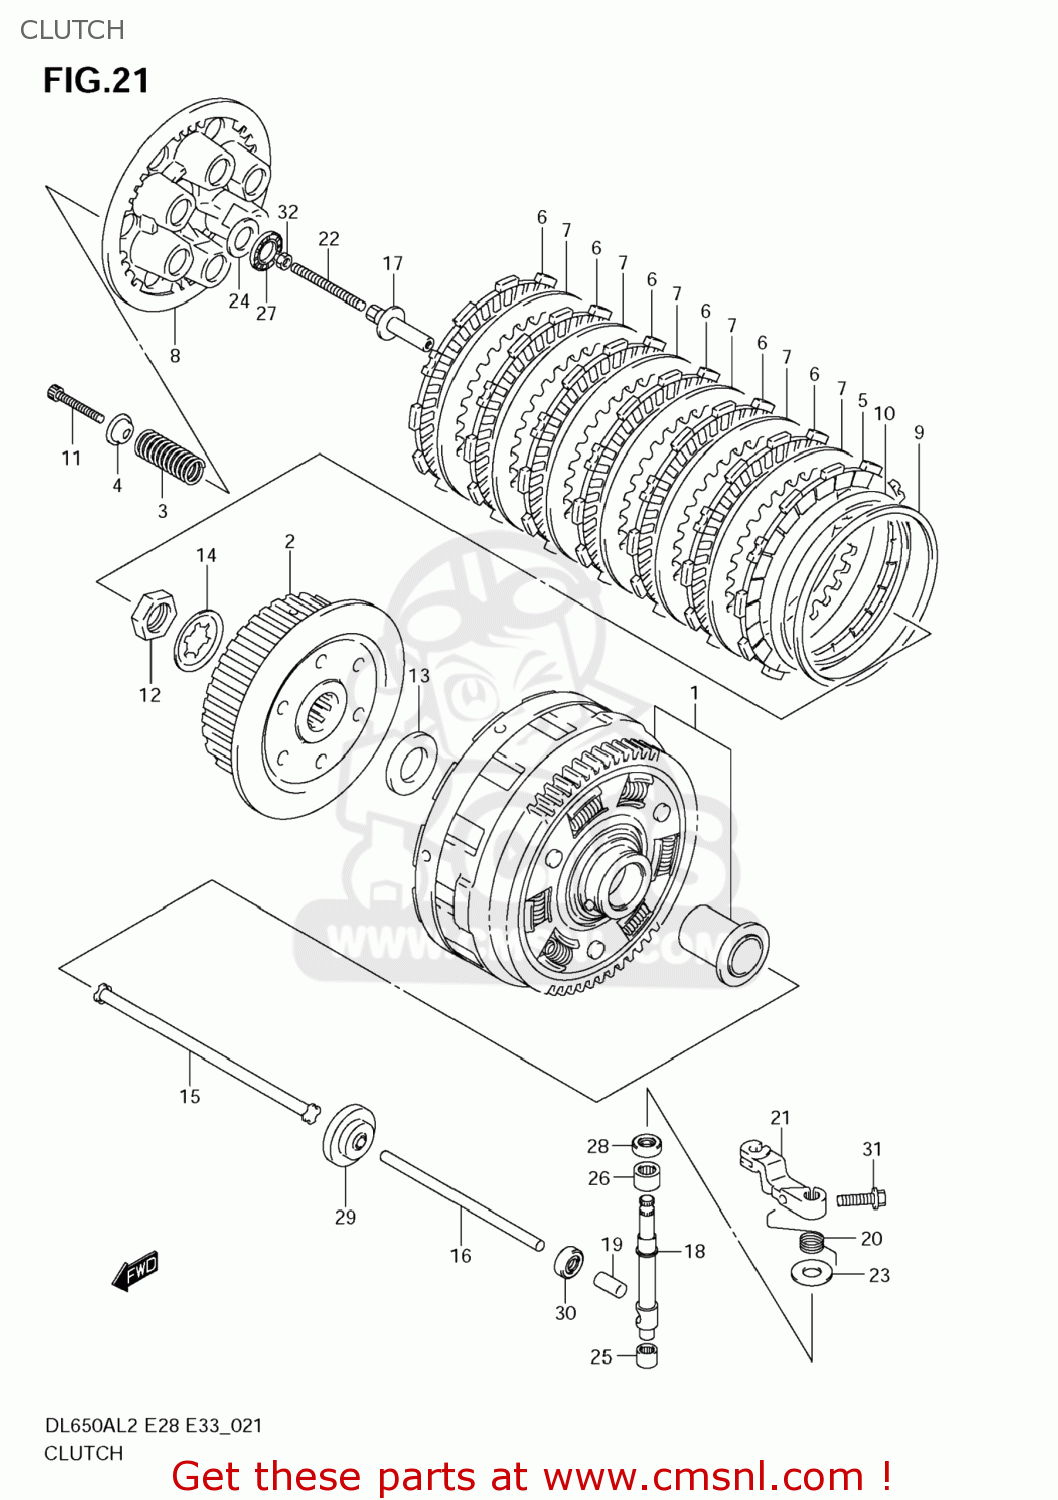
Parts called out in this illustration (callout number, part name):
1	GEAR ASSY,PRI DRIVEN
2	HUB,CLUTCH SLEEVE
3	SPRING,CLUTCH
4	WASHER
5	PLATE,CLUTCH DRIVE NO.2 (NAS)
6	PLATE,CLUTCH DRIVE (NAS)
7	PLATE,CLUTCH DRIVEN(T:1.6) (NAS)
8	DISC,CLUTCH PRESSURE
9	SEAT,WAVE WASHER
10	WASHER,CLUTCH PLATE WAVE
11	BOLT,CLUTCH SPRING
12	NUT
13	WASHER(20X36X3)
14	WASHER,LOCK
15	ROD,PUSH,R
16	ROD,CLUTCH PUSH,L
17	PIECE,CLUTCH PUSH
18	CAMSHAFT,CLUTCH RELEASE
19	CAP,CLUTCH PUSH ROD
20	SPRING,CLUTCH RELEASE RETURN
21	ARM,CLUTCH RELEASE
22	SCREW(6X73)
23	WASHER(10.5X24X1)
24	WASHER(15.5X28X1)
25	BEARING(10X14X10)
26	BEARING(12X18X12)
27	BEARING(15X28X2)
28	SEAL,OIL(10X20X6)
29	SEAL,OIL(6X34X10.5)
30	SEAL,OIL(10X17X5)
31	BOLT
32	NUT
